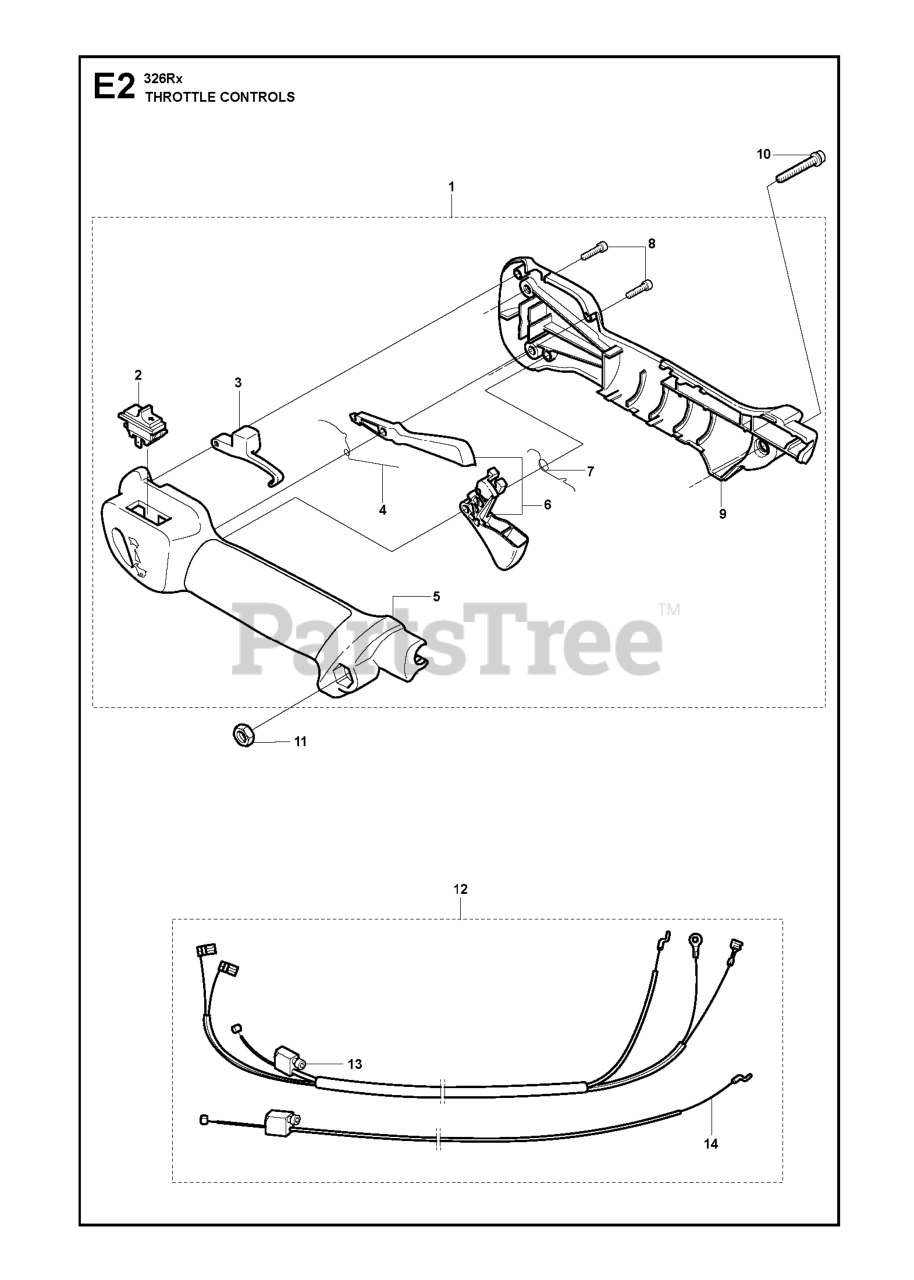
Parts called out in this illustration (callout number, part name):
1	HANDLE SYSTEM ASSY
2	STOP BUTTON
3	LOCKOUT STARTER THROTTLE
5	HANDLE
6	THROTTLE CONTROL
8	SCREW
10	SCREW
12	CABLE HARNESS COMPLETE
13	SCREW
14	THROTTLE WIRE
